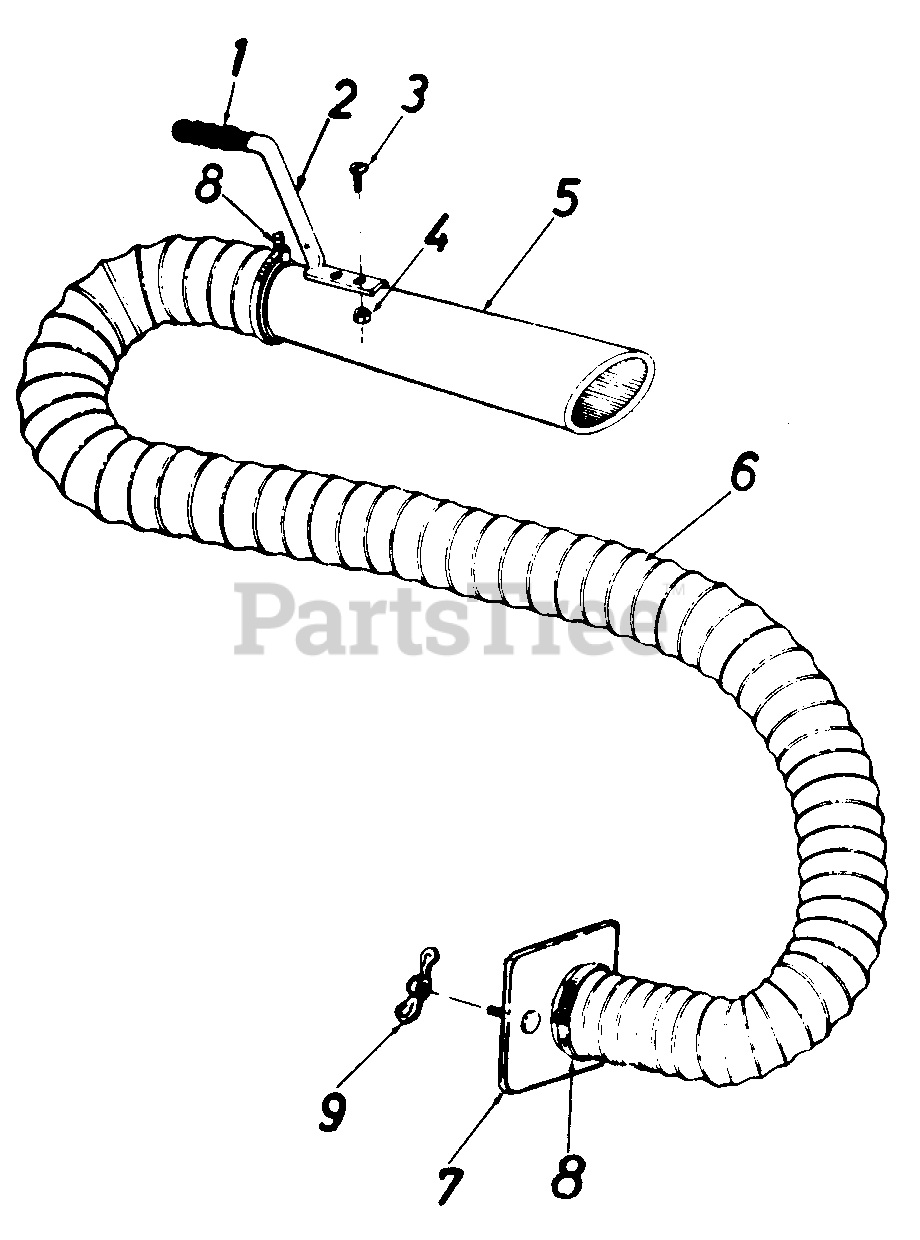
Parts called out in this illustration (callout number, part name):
1	Handle Grip
2	Handle
3	Truss Serns Scr. 10-24 x 1/2" Lg.*
4	Hex Nut 10-24 Thd. Lg.
5	Hose Nozzle
6	Flexlble Hose 4" Dia. x 10' Lg.
7	Hose Adapter Plate
8	Hose Clamp - For 4" Dia. H ose
9	Wing Nut 1/4-20Thd.
